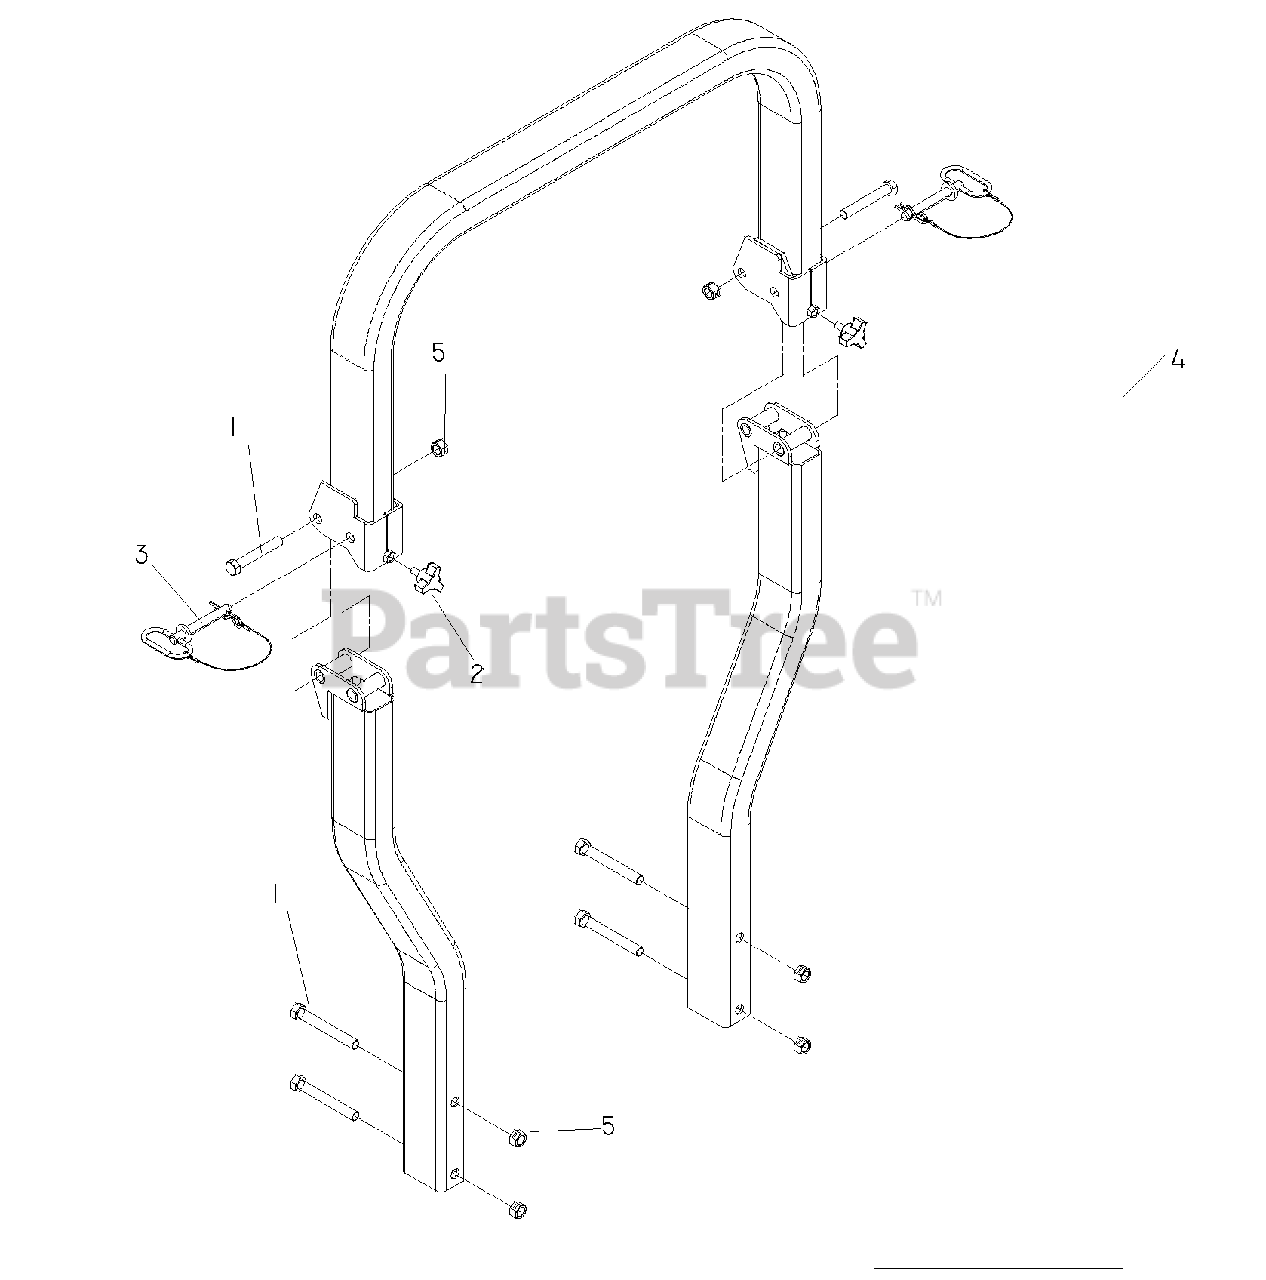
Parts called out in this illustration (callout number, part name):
1	HCS 1/2C X 3 1/4
2	KNOB W/STUD
3	PIN, 1/2" W/LANYARD
4	ROLL OVER PROTECTION SYSTEM
5	NUT 1/2-13 HEX CNTRLK GR 5 ZD
